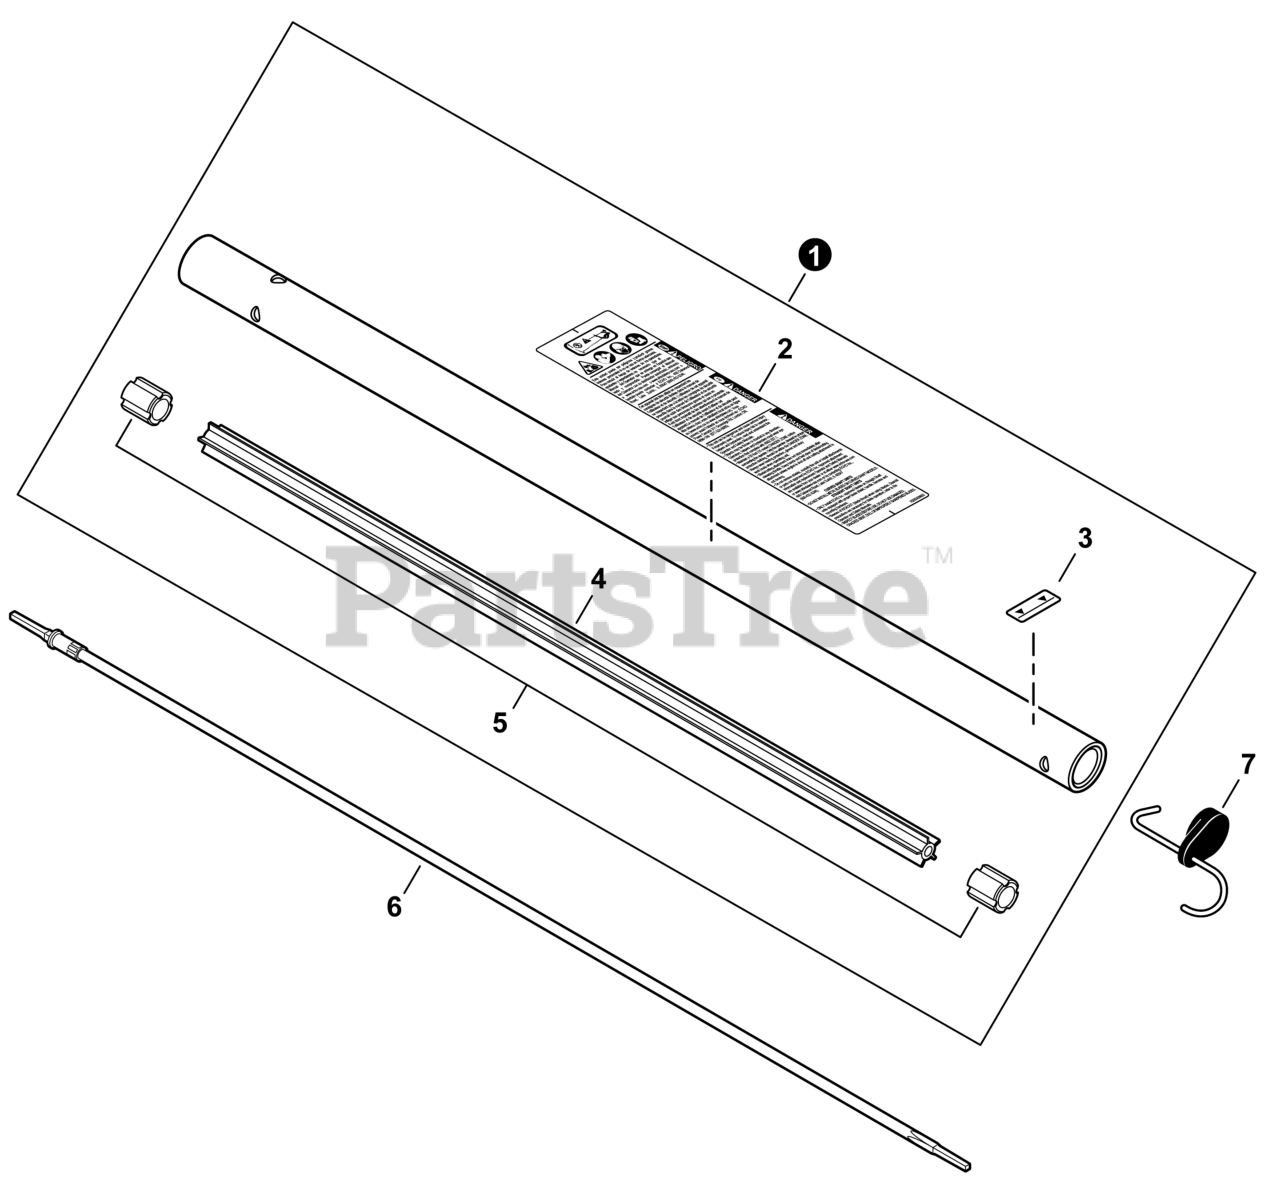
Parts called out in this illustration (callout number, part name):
1	MAIN PIPE ASSY
2	LABEL - CAUTION
3	LABEL - ALIGNMENT
4	LINER - FLEXIBLE
6	DRIVESHAFT - FLEXIBLE
7	HANGER, ATTACHMENT
